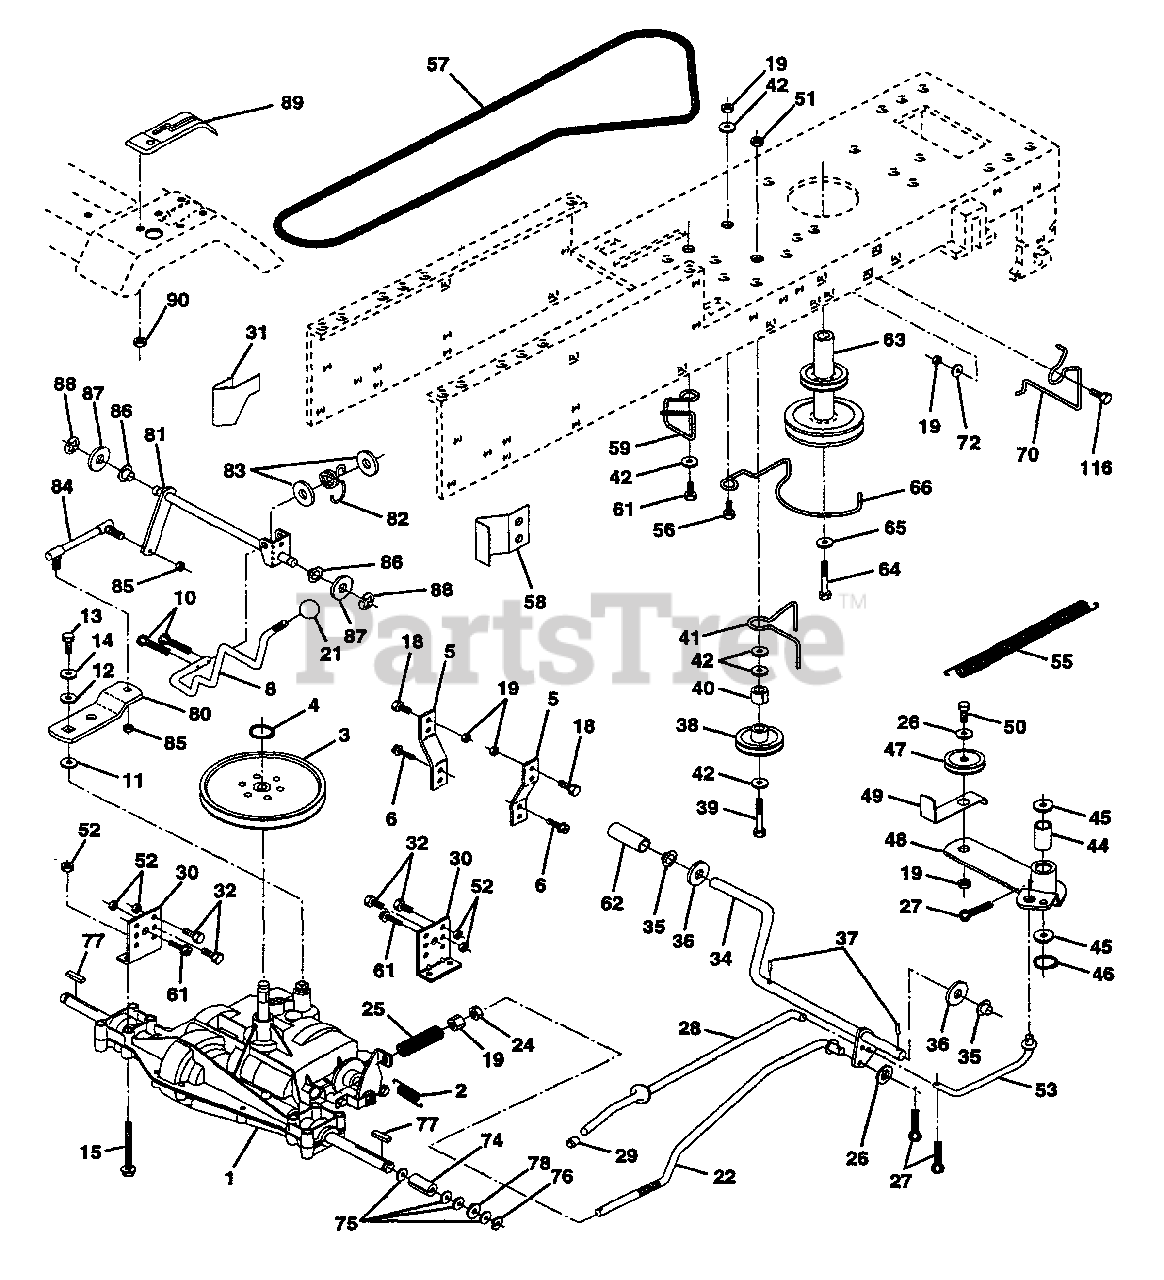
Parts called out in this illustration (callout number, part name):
1	Transaxle 6sp Dana 4360-96
2	Spring Return Brake T/a Zinc
3	Pulley Transaxle 18" tires
4	Ring Retainer # 5100-62
5	Strap Torque 30 Degrees
6	Screw Thdrol 5/16-18 X 3/4 TYT
8	Rod Shifter
10	Pin Cotter 1/8 X 1 Cad
11	Washer Plate Shf 388 Sq Hole
12	Washer 15/32 X 3/4 X 16 Ga
13	Bolt 1/4-28 Unf Gr 8 W/Patch
14	Washer Lock Hvy Helical 1/4
15	Bolt Hex 5/16-18FLGHD Gr. 5
18	Bolt Fin Hex 318-16unc X 1 Gr. 5
19	Nut Lock 3/8-16 Unc
21	Knob Duckhead 1/2-13 Plstc Thds Blk
22	Rod Brake Blk Zinc 26 840
24	Nut Hex Jam 3/8-16 Unc
25	Spring Rod Brake 2 00 Zinc
26	Washer 13/32 X 13/16 X 16 Ga
27	Pin Cotter 1/8 X 3/4 Cad
28	Rod Brake Parking LT/YT
29	Cap Brake Parking Black
30	Bracket Mtg Transaxle
31	Keeper Belt LH LT 14 Ga
32	Bolt Hex Hd 5/16-18unc X 3/4
34	Shaft Asm Pedal Foot
35	Bearing Nylon Bk 629 Id
36	Washer 21/32 X 1 X 16 Ga
37	Pin Roll 3/16 X 1"
38	Pulley Idler Flat
39	Bolt Fin Hex 3/8-16unc X 2-3/4
40	Spacer Split 395 X 59 Bzp
41	Keeper Belt Retainer
42	Washer 13/32 X 13/16 X 12 Ga
44	Bearing Nyl 503 X 628 X 1 25
45	Washer Hardened
46	Ring Klip #t5304-50
47	Pulley Idler V Groove Plastic
48	Bellcrank Asm Clutch
49	Retainer Belt Style Spring
50	Bolt Hex Hd 3/8-16unc X 1-1/2
51	Nut Crownlock 3/8-16 Unc
52	Nut Crownlock 5/16-18 Unc
53	Link Clutch 7 66
55	Spring Return Clutch 6 75
56	Bolt Fin Hx 3/8-16 X 1/4
57	V-Belt Ground Drive 95 25 42"
58	Keeper Belt RH LT Pnt/zinc 16g
59	Keeper Belt Span Ctr
61	Screw Thdrol 3/8-16x3/4 Ty-tt
62	Cover Pedal Blk Round
63	Engine Pulley LT/YT
64	Bolt Hex 7/16-20 x 4 Gr. 5
65	Washer Lock Hvy Hlcl Spr 7/16
66	Keeper Belt Engine LH LT
70	Guide Belt Mower Drive RH
72	Washer 13/32 X 1-1/4 X 12 Ga
74	Spacer Split
75	Washer 25/32 X 1 1/4 X 16 Ga
76	E-ring #5133-75
77	Key Square 2 0 X 1845/ 1865
78	Washer 25/32 X 1-5/8 X 16 Ga
80	Arm Shift Transaxle
81	Shaft Asm Cross 20"t 42" deck
82	Spring Torsion T/a
83	Washer 17/32 X 3/4 X 16 Ga
84	Rod Shift Adj Tie
85	Nut, Centelock 1/4 - 28
86	Bushing Rod Strg 629/632 Id
87	Washer 21/32 X 1-1/4 X 16 Ga
88	Ring Klip #5304-62
89	Console Shift 6sp LT
90	Nut Self-thd Wsh-hd 1/4 Zinc
